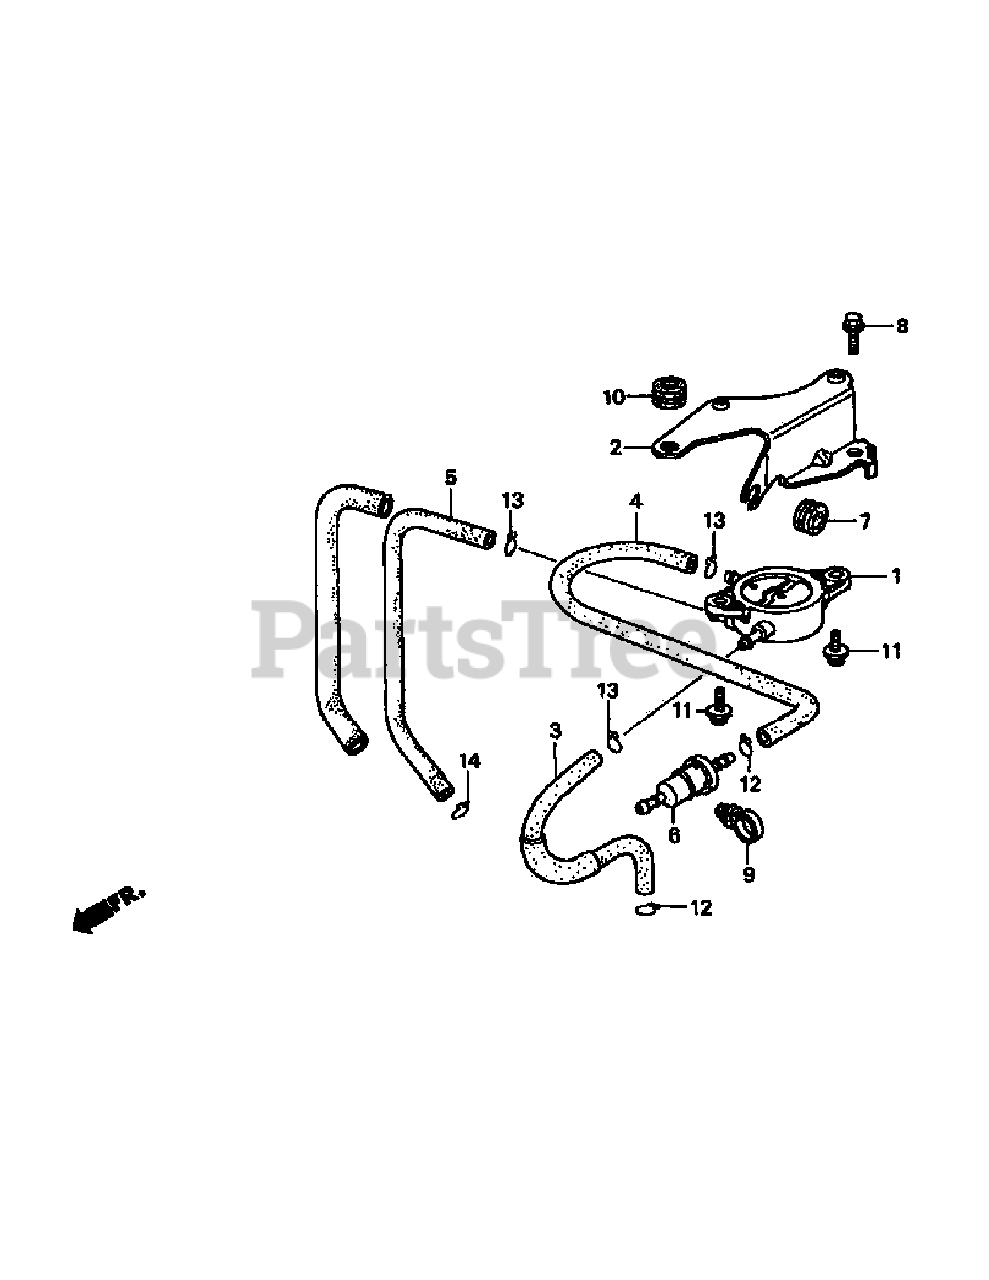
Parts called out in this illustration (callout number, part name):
1	Fuel Pump Assy.
2	Fuel Pump Bracket
3	Fuel Line To Carburetor
4	Fuel Line To Filter
5	Diaphragm Line
6	Fuel Filter
7	Reserve Tank Grommet
8	Flange Bolt (6x14)
9	Wire Harness Clip
10	Pump Bracket Grommet
11	Screw Washer (6x16)
12	Tube Clip
13	Tube Clip
14	Tube Clip
